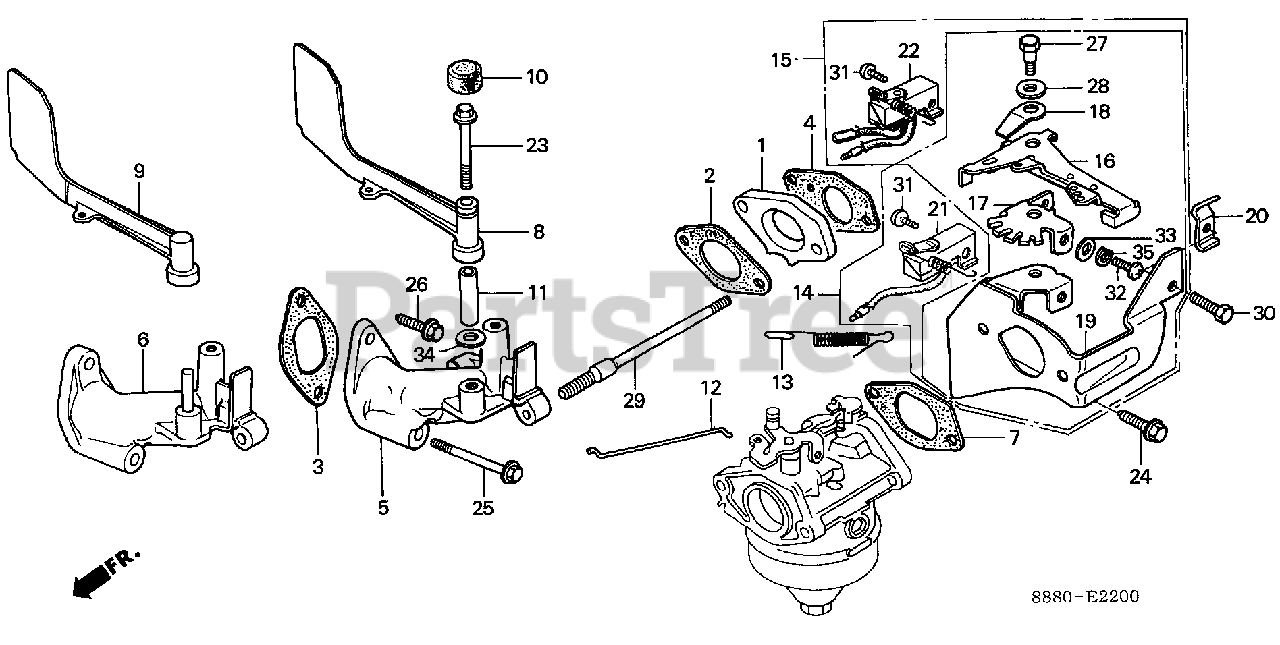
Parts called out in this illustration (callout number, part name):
1	INSULATOR, CARBURETOR
2	GASKET, INSULATOR
3	GASKET, MANIFOLD
4	GASKET, CARBURETOR
5	MANIFOLD, IN.
7	GASKET, AIR CLEANER
8	FLUTTER, GOVERNOR (NOT AVAILABLE)
10	SEAL, FLUTTER
11	COLLAR, FLUTTER (NOT AVAILABLE)
12	ROD, GOVERNOR
13	SPRING, GOVERNOR
15	CONTROL ASSY.
16	LEVER, CONTROL
17	PLATE, LEVER SETTING
18	SPRING, LEVER SETTING (NOT AVAILABLE)
19	STAY, CLEANER CASE
20	HOLDER, WIRE
22	SWITCH ASSY., ENGINE STOP
23	BOLT, FLANGE (6X40) (CT200)
24	BOLT, FLANGE (6X12) (CT200)
25	BOLT, FLANGE (6X50)
26	BOLT, FLANGE (6X20) (CT200)
27	BOLT, CONTROL LEVER
28	WASHER (7MM) (NOT AVAILABLE)
29	BOLT, STUD (6X141) (NOT AVAILABLE)
30	BOLT, HEX. (6X12)
31	SCREW, PAN (4X8)
32	SCREW, PAN (5X8)
33	WASHER, PLAIN (5MM)
34	WASHER, PLAIN (6MM)
35	WASHER, SPRING (5MM)
